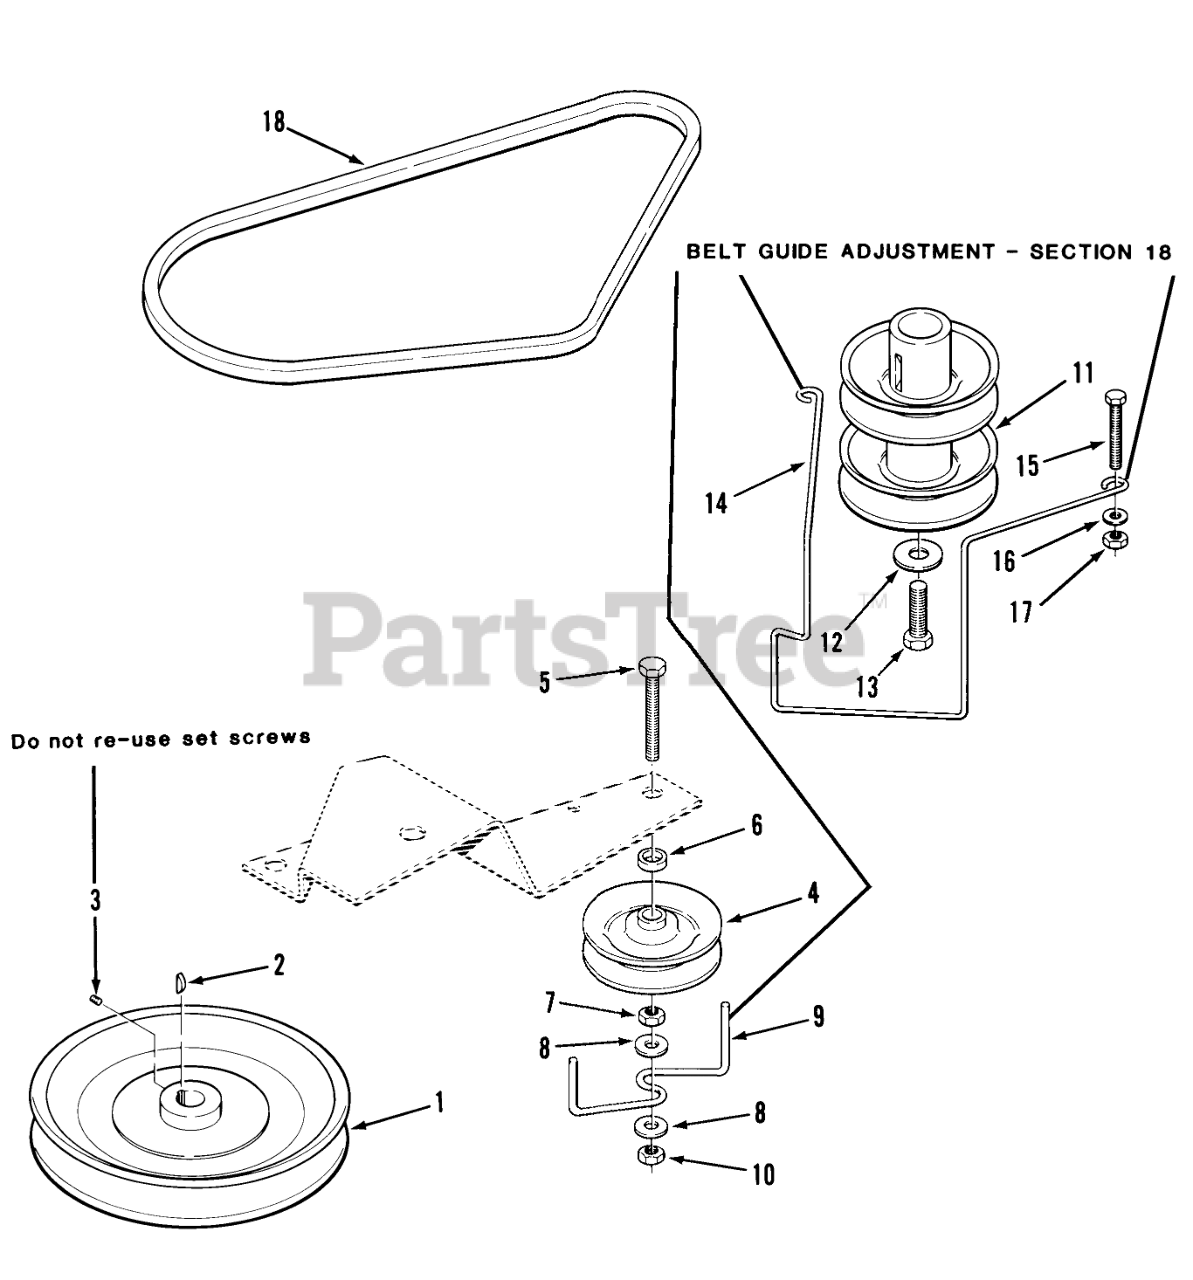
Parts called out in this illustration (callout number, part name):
1	Transmission Pulley
2	KEY-HI-PRO
3	HEX HD CAP SCREW
4	PULLEY-IDLER STATION
5	Bolt
6	SPACER
7	Nut
8	Washer
9	GUIDE - BELT
10	NUT
11	PULLEY ENGINE
12	WASHER
13	HEX HD CAP SCREW
14	Engine Pulley Belt Guide
15	HHCS
16	WASHER 5/16 SAE
17	Nut
18	Transmission Drive Belt
